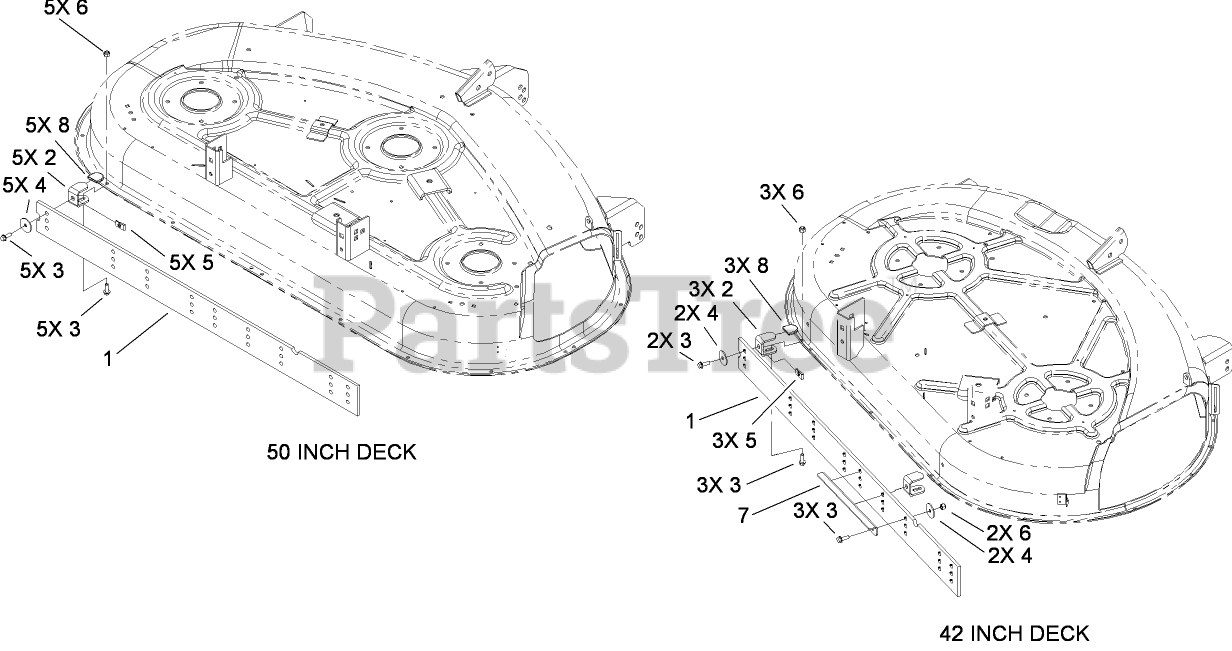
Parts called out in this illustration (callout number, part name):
2	BRACKET-MOUNTING
3	SCREW-HHF
4	WASHER-FLAT
5	NUT-SPEED
6	NUT-LOCK, NI
